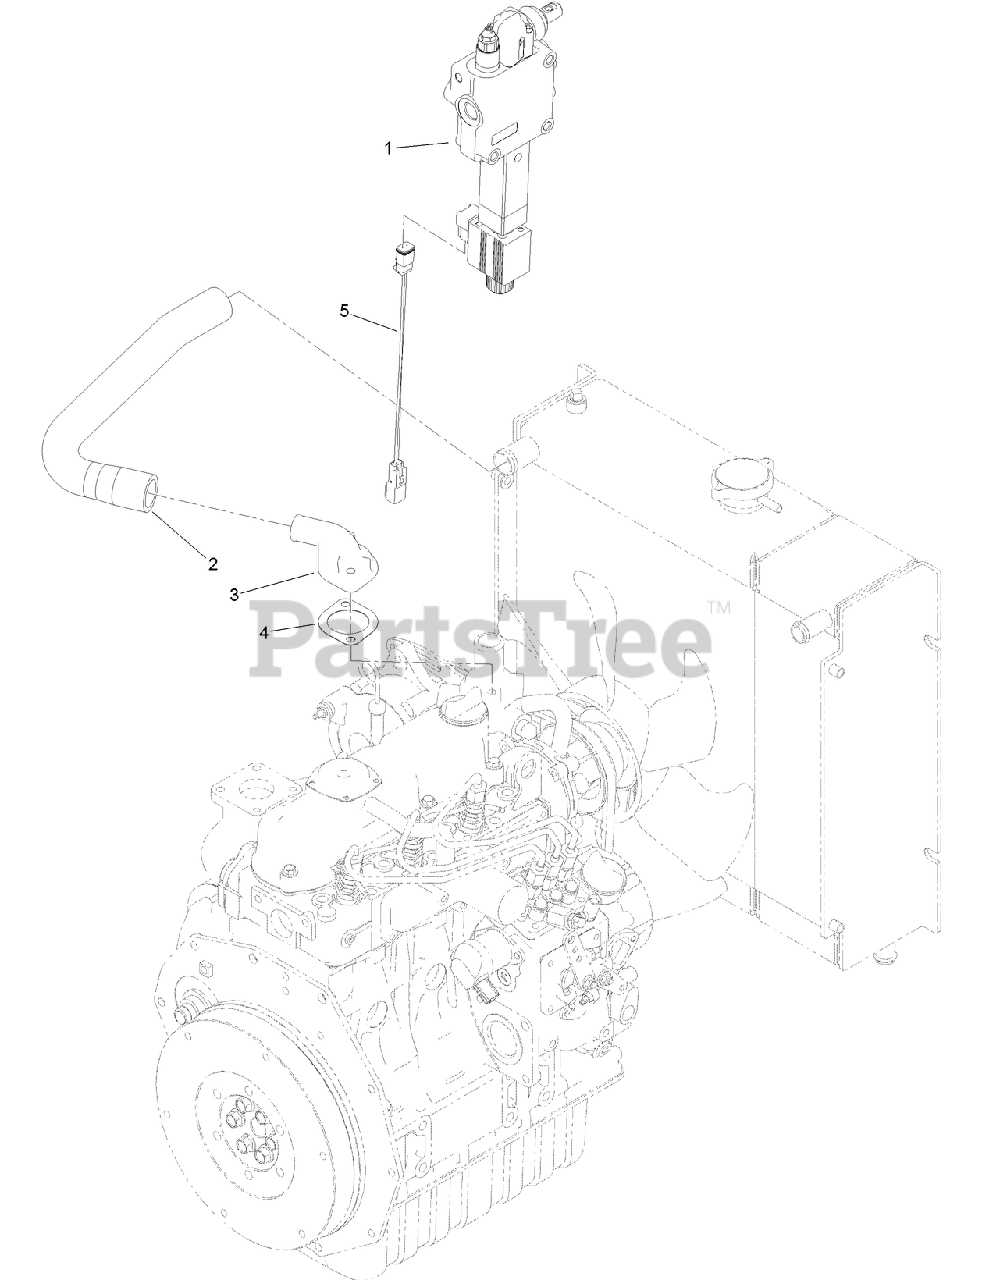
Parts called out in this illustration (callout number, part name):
1	DOUBLE DETENT VALVE ASM
2	HOSE-RADIATOR
3	OUTLET-WATER
4	GASKET-THERMOSTAT
5	HARNESS-WIRE
